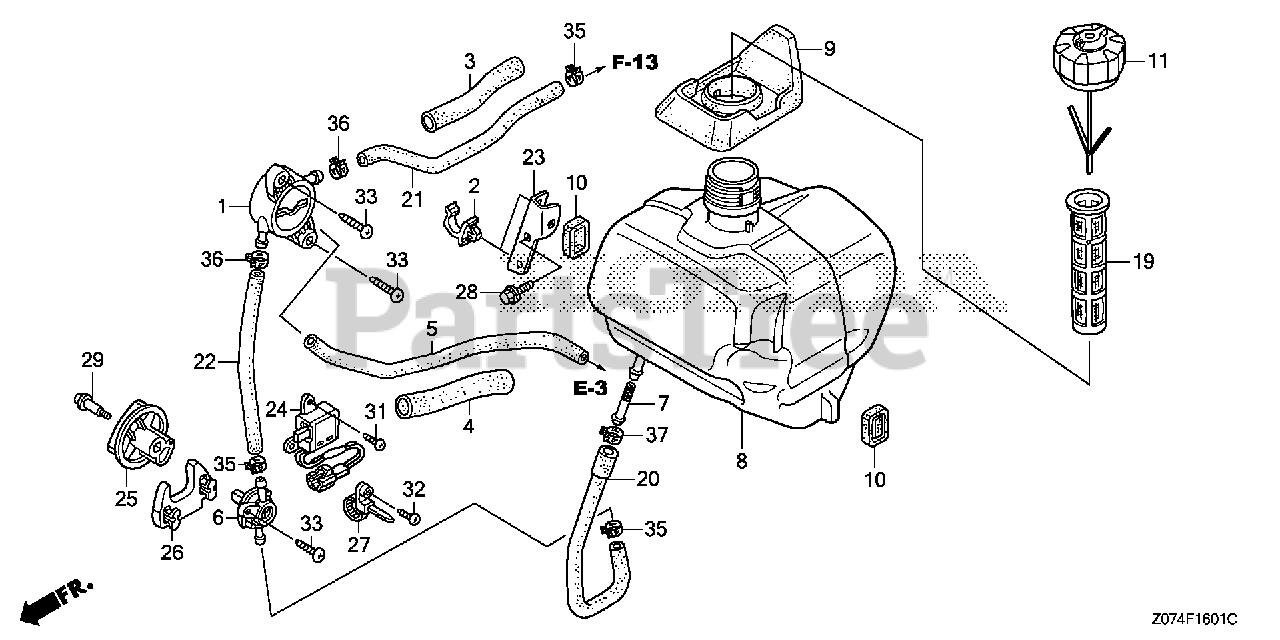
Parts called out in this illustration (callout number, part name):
1	PUMP ASSY., FUEL (MSDS)
2	CLIP, TUBE
3	RUBBER A, SUPPORTER
4	RUBBER B, SUPPORTER
5	TUBE, DIAPHRAGM
6	PETCOCK ASSY.
7	FILTER, FUEL
8	TANK, FUEL (COO)(FOR U.S.A.)
9	SEAL, FUEL FILLER NECK
10	RUBBER A, TANK MOUNTING
11	CAP ASSY., FUEL TANK
12	INNER, FUEL CAP (NOT AVAILABLE)
13	SPONGE, FUEL CAP BREATHER
14	GASKET, FUEL CAP
15	VALVE, BREATHER
16	SPRING, FUEL CAP
17	GASKET, BREATHER VALVE (NOT AVAILABLE)
18	TETHER, FUEL CAP
19	FILTER, FUEL
20	TUBE, FUEL TANK (FKM)
21	TUBE A, FUEL (FKM)
22	TUBE B, FUEL (FKM)
23	BRACKET, FUEL TUBE
24	SWITCH ASSY., ENGINE STOP
25	KNOB, ENGINE SWITCH
26	PLATE, ENGINE SWITCH
27	BAND, HARNESS
28	BOLT, FLANGE (6X12) (CT200)
29	SCREW, PAN (4X19)
30	COLLAR, RR. FENDER
31	SCREW, TAPPING (3X12)
32	SCREW, TAPPING (3X16)
33	SCREW, TAPPING (5X20) (PO)
34	PIN, LOCK (6MM)
35	CLIP, TUBE (D8)
36	CLIP, TUBE (D8.5)
37	CLIP, TUBE (10.5MM)
39	GASKET KIT, BREATHER VALVE
